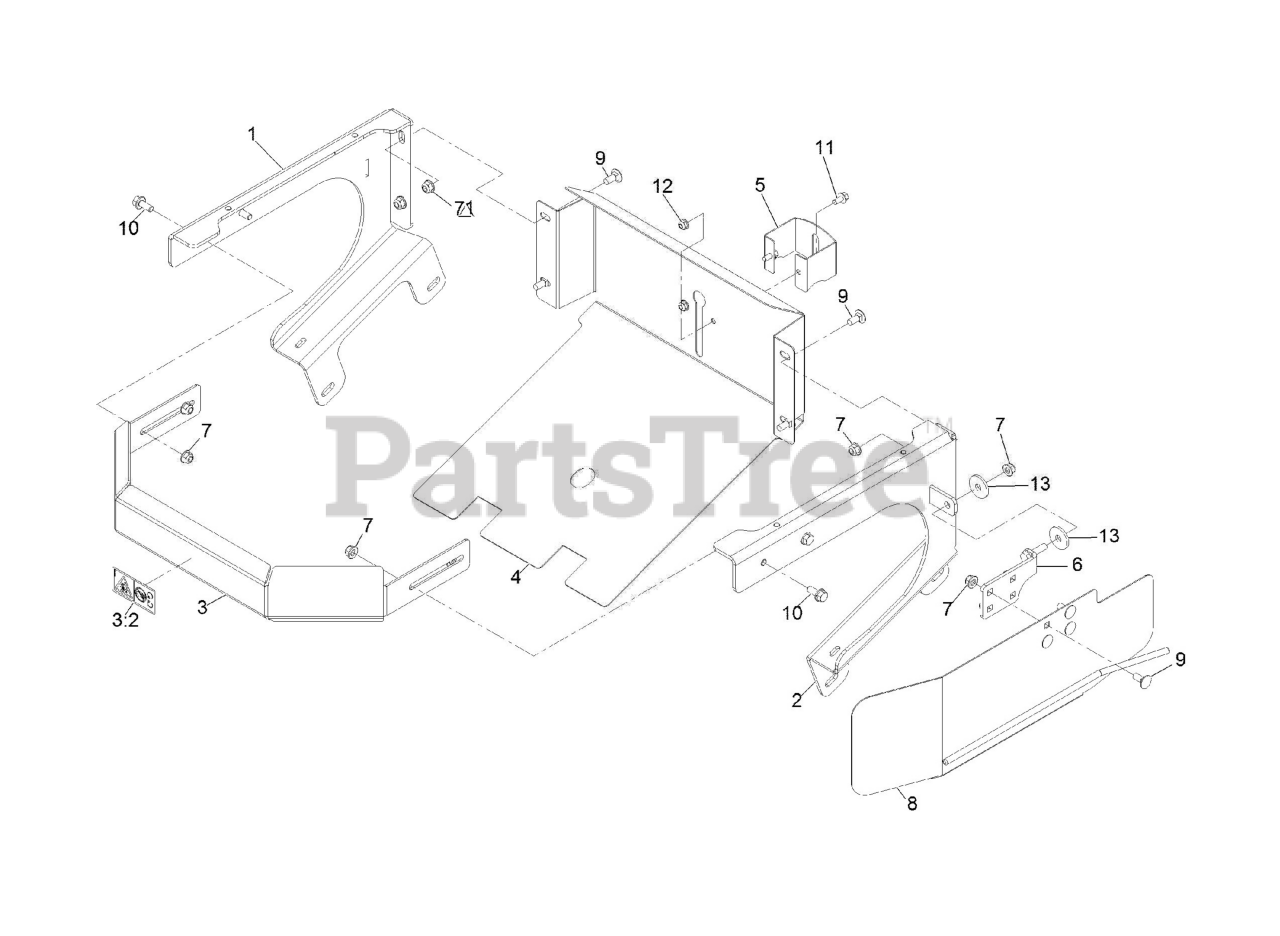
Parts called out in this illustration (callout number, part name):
1	FRAME-HOPPER, RH
2	FRAME-HOPPER, LH
3	BUMPER-FRONT
3:2	Decal-Dismemberment Hazard
4	BACKSHIELD, AE HOPPER
5	BRACKET-CABLE, HOPPER
6	MOUNT-DEFLECTOR
7	Nut-Hex Flange
8	DEFLECTOR-ZPLUG
9	SCREW-CARR
10	SCREW-HHF
11	SCREW-HHF
12	Nut-Hex Flange
13	WASHER
